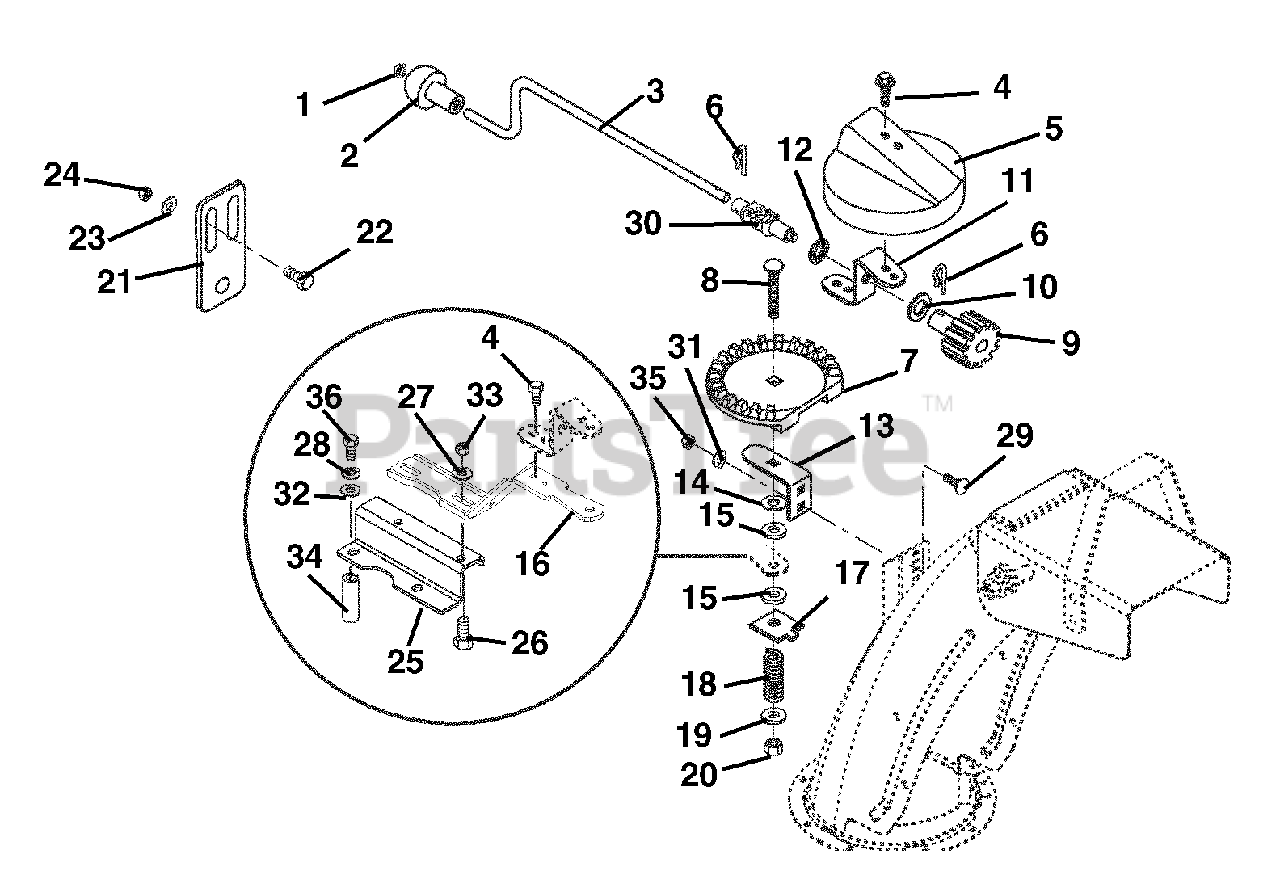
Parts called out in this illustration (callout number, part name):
1	CAP, 3/8 ROD YWZC
3	CRANK, CHUTE
4	@SCR-TAP .25-20X.50 HWH TR YWZ
5	GEAR COVER
6	PIN, SPRING CLIP
7	CHUTE GEAR
8	@BLT-RDHDSQNK .38-16X2.50 G5YZ
9	PINION GEAR W/BRACKET
10	WSHR-FL-STL .630X1.005X.062 YZ
11	BRACKET-GEAR
12	PUSHNUT .625
13	GEAR STRAP
14	WSHR-FL-STL .380X1.50X.062 YWZ
15	FRICTION WASHER
16	BRACKET, CHUTE SUPPORT
17	FRICTION PLATE
18	SG-COMP .187X.56X1.62
19	@WSHR-FL-STL.406X.812X.065 YWZ
20	@NUT-LK-CTR .38-16 YWZC
21	BRACKET, CHUTE CRANK SUPPORT
22	@BLT-HEX .25-20X.50 GR5 YWZC
23	@WSHR-FL-STL.281X.62X.065 YWZC
24	@NUT-LK-CTR .25-20 YWZC
25	BRACKET, ENGINE - CHUTE
26	@BLT-HEX .31-18X.75 GR5 YWZC
27	@WSHR-FL-STL.312X.734X.065 YWZ
28	@WSHR-LK .31X.078 REG YWZC
29	@BLT-RDHDSQNK .25-20X.75 G5YZ
30	ASS'Y, UNIVERSAL-W/PIN END
31	@WSHR-LK .25X.062 REG YWZC
32	@WSHR-FL-STL.344X.688X.065YWZC
33	@NUT-LK-CTR .31-18 YWZC
34	SPACER .322X.626X.50
35	@NUT-HEX .25-20 YWZC
36	@BLT-HEX .31-18X1.25 GR5 YWZC
